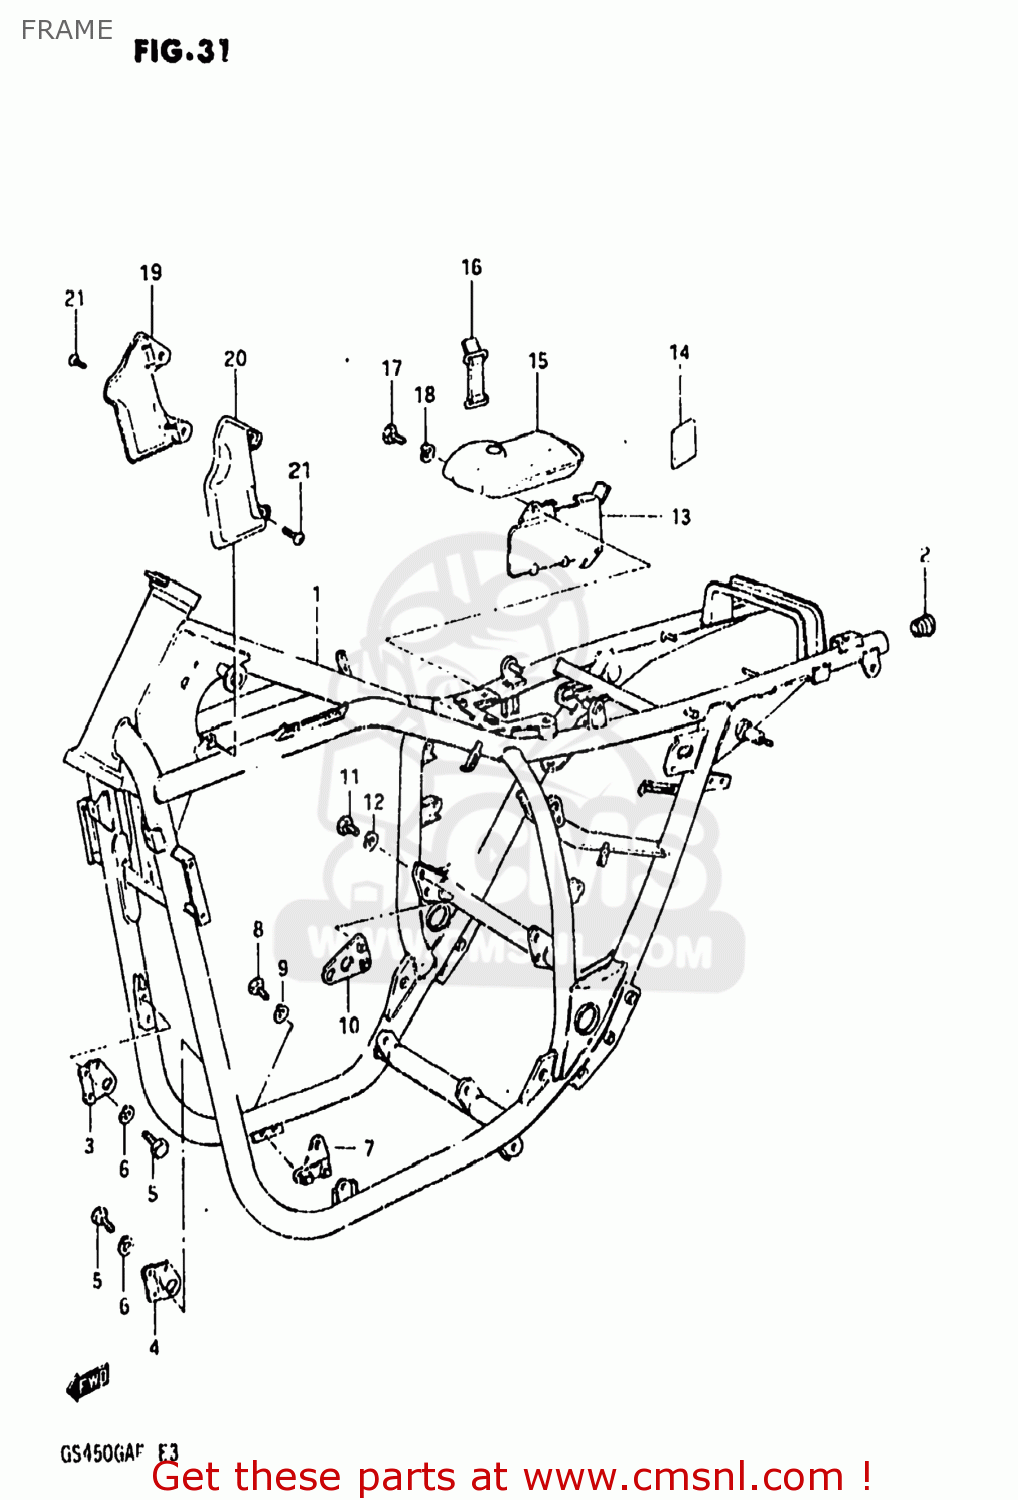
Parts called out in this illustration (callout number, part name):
1	FRAME
2	CAP(OD:26)
3	PLATE,ENGINE MOUNTING
4	PLATE,ENGINE MOUNTING
5	BOLT
6	LOCK WASHER
7	PLATE,MOUNTING NO.2,LEFT
8	BOLT
9	LOCK WASHER
10	PLATE,ENGINE MOUNTING
11	BOLT
12	LOCK WASHER
13	HOLDER,TOOL
14	PROTECTOR(170X95X3.0)
15	TOOL SET
16	BAND
17	BOLT
18	LOCK WASHER
19	COVER,FRAME HEAD,RIGHT
20	COVER,FRAME HEAD,LEFT
21	SCREW M5X12 DIN 7985/N
